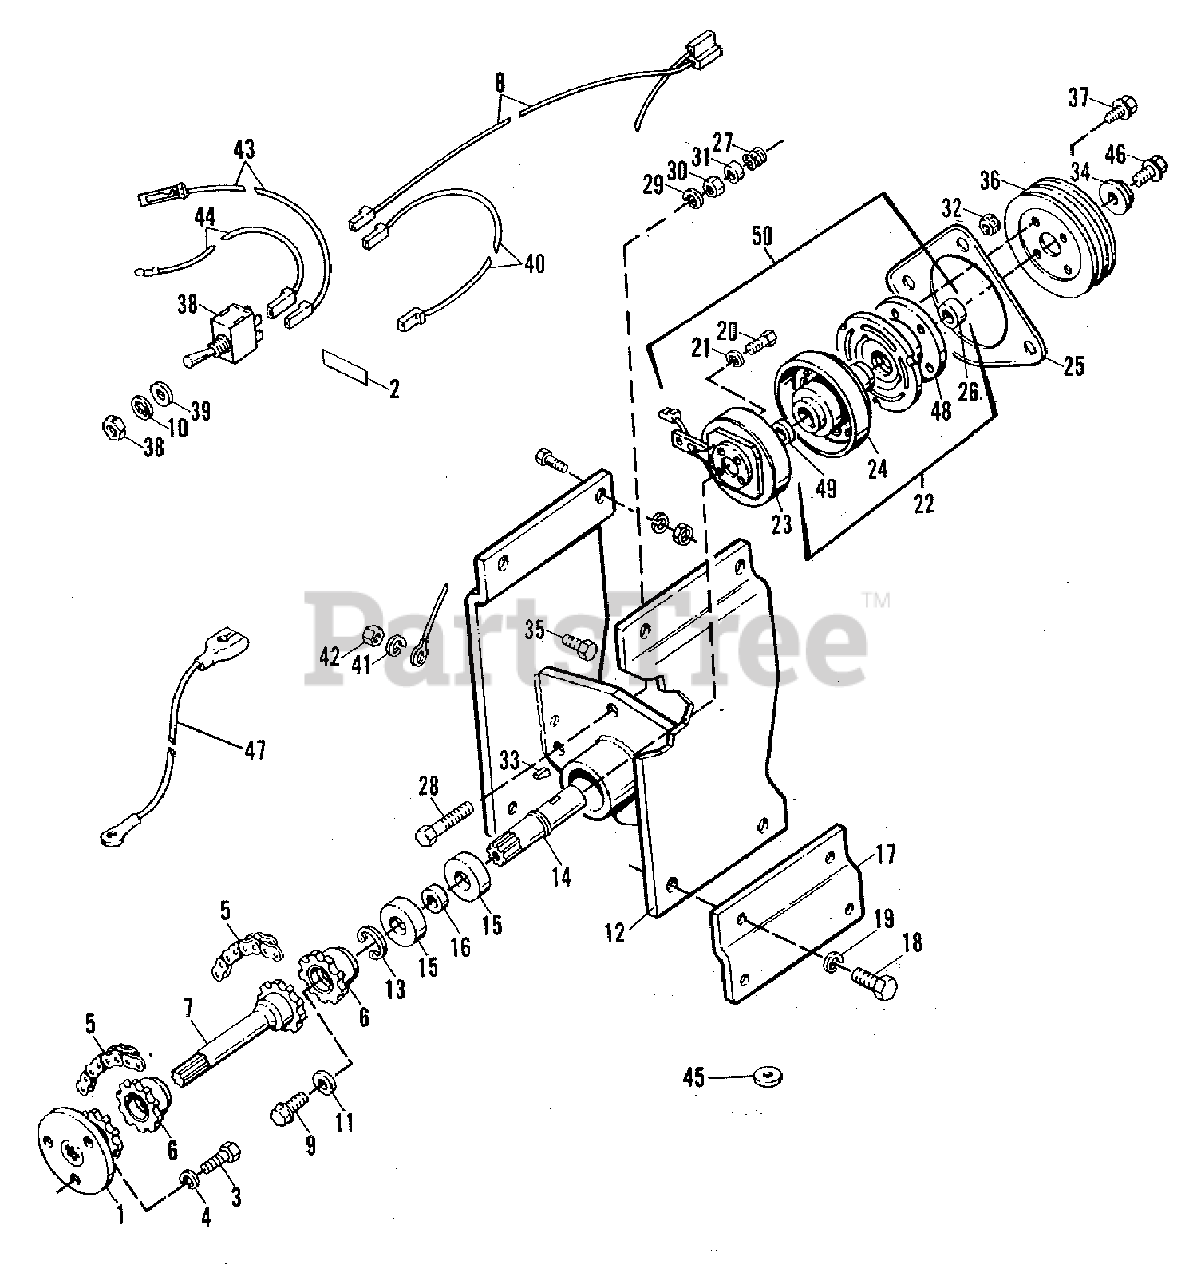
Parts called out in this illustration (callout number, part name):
1	DRIVE ASSEMBLY, Crankshaft
2	DECAL, Clutch
3	CAPSCREW, M10 x 1-1/4MM
4	LOCKWASHER, 7/16
5	CHAIN, 3/4 Pitch (11 Links)
5	CHAIN, 3/4 Pitch, Bulk (10 Ft. Roll)
5	CHAIN, 3/4 Pitch, Bulk (50Ft. Roll)
5	LINK, Roller
5	LINK, Offset
5	LINK, Connecting
6	SPROCKET ASSEMBLY
7	SPROCKET ASSEMBLY (Prior S/N 5020-1401)
7	SPROCKET ASSEMBLY (Eff. S/N 5020-1401 & Up)
8	WIRE ASSEMBLY, Clutch
9	CAPSCREW, Whizlock, 3/8NC x 3/4
10	LOCKWASHER, Internal Tooth, 1/2
12	SUPPORT ASSEMBLY, Battery
12	CAPSCREW, 1/2NC x 1-1/4
12	LOCKWASHER, 1/2
13	RING, Retaining
18	CAPSCREW, M12 x 1-1/2 x 35MM
19	LOCKWASHER, 1/2
20	SCREW, Special
22	ROTOR & ARMATURE KIT, Front Clutch (Includes Items 24, 26, 48 & 50)
23	FIELD ASSEMBLY
24	ROTOR & ARMATURE ASSEMBLY
25	DRUM, Brake
27	SPRING, Compression
28	CAPSCREW, Full Thread, 3/8NF x 2-1/2
29	LOCKWASHER, 3/8
32	NUT, Lock, 3/8NF
35	CAPSCREW, 1/4NC x 3/4
36	PULLEY, Electric Clutch
37	SCREW, Taptite, 3/8NC x 3/4
40	WIRE ASSEMBLY, Power
41	LOCKWASHER, 1/4
43	WIRE, Safety Switch
44	WIRE, Safety Switch
46	CAPSCREW, Whizlock, 3/8NC x 1-1/4
47	CABLE, Battery
48	FLANGE ASSEMBLY, Brake Shoe
49	SPACER, Rotor
50	CLUTCH KIT, Front, Electric
